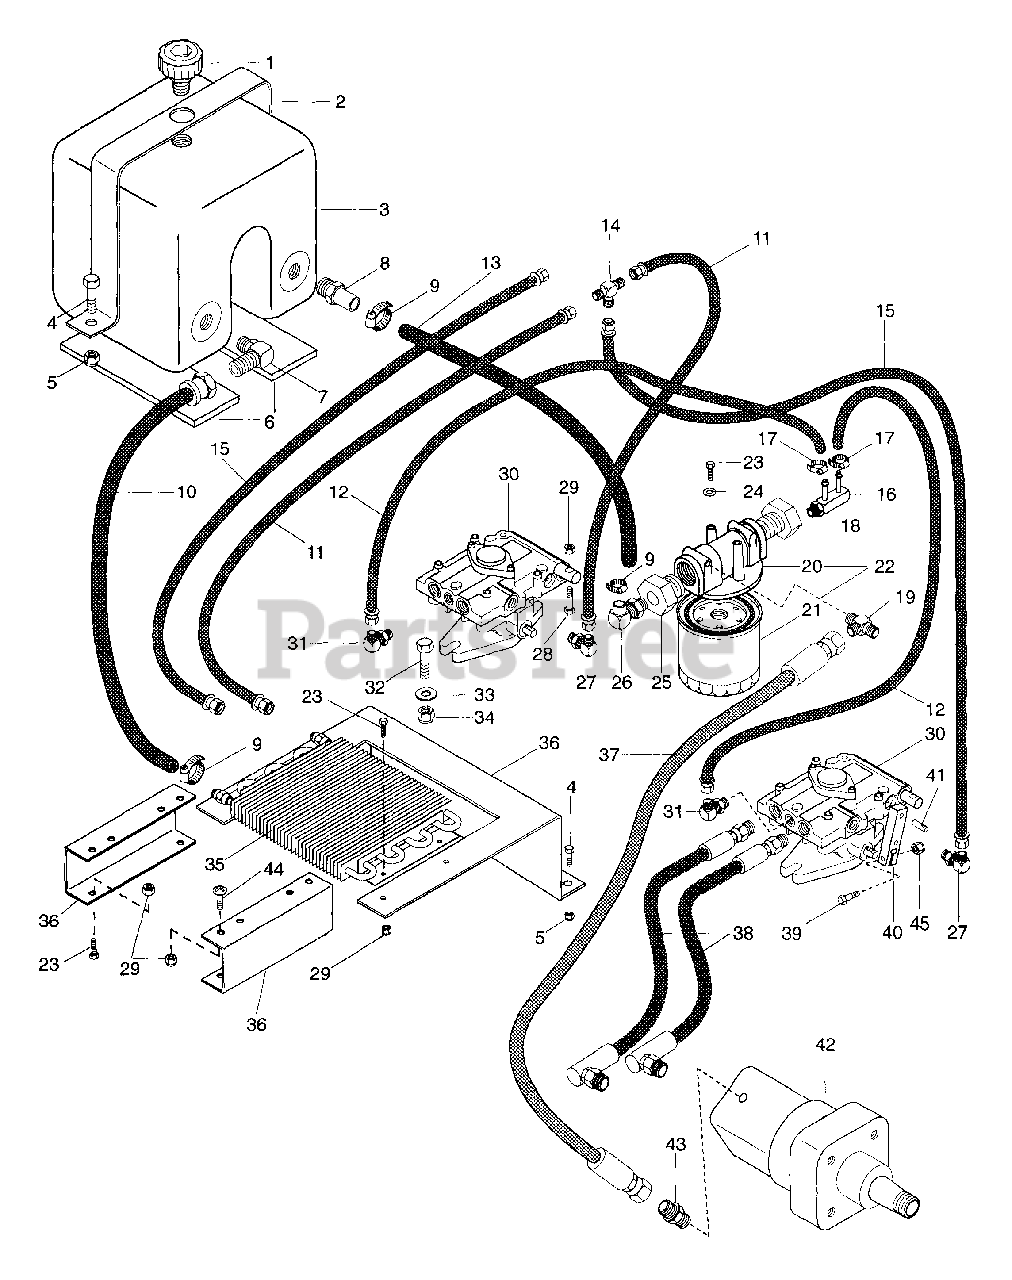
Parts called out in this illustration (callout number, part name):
1	Cap, Filter
2	Strap, Tank
3	Tank, Hydraulic
4	Bolt-Hex .31-18 x .75 Grade 5
5	Nut-Locking-Nylon .312-18 Grade 2
6	Pad, Gas Tank
7	Adapter - .37-.875
8	Fitting - Adapter 88-14
9	Clamp, .88 Diameter Hose
10	Hose, Hydraulic Cooler to Tank
10	Hose, Hydraulic Oil Cooler to Tank
11	Hose, Hydraulic Valve to Tank
12	Hose, Oil Filter to Pump
13	Hose, .50 Inside Diameter x .75 OD
14	Adapter - Tee .56-18
15	Hose, Pump to Tee
16	Fitting-Pipe .563-18
17	Clamp-Hose 1.50 x .81 x 1.42
18	Adapter, Hydraulic 6410-12-06
19	Adapter, Hydraulic 2601-04-04-04
20	Head, Oil Filter
21	Replacement Element 921999
22	Assembly, Filter
23	Bolt-Hex .25-20 x .63
24	Washer-Lock .250 Regular
25	Adapter-Hydraulic .88-14
26	Fitting
27	Adapter 2503-6-6
28	Bolt-Hex .25-20 x 2.00 Grade 5
29	Nut-Locking-Nylon .250-20 Grade 2
30	Variable Displace Pump
31	Adapter 2503-6-4
32	Bolt-Hex .38-16 x 1.125
33	Washer-Flat-Steel .406 x .812 x .065
34	Nut-Locking-Center .625-10 Grade 2
35	Cooler, Oil
36	Bracket, Oil Cooler
37	Hose Assembly, Motor to Oil Filter
38	Assembly, Hose Wheel Motor to Pump
39	Bolt-Hex .25-20 x 1.25 Grade 5
40	Arm, Pump Actuating
41	Pin-Dowel .312 x 1.25
42	Motor, Wheel
43	Adapter 0503-4-4
44	Screw-Machine .25-20
45	Nut-Locking-Flange .250-20
